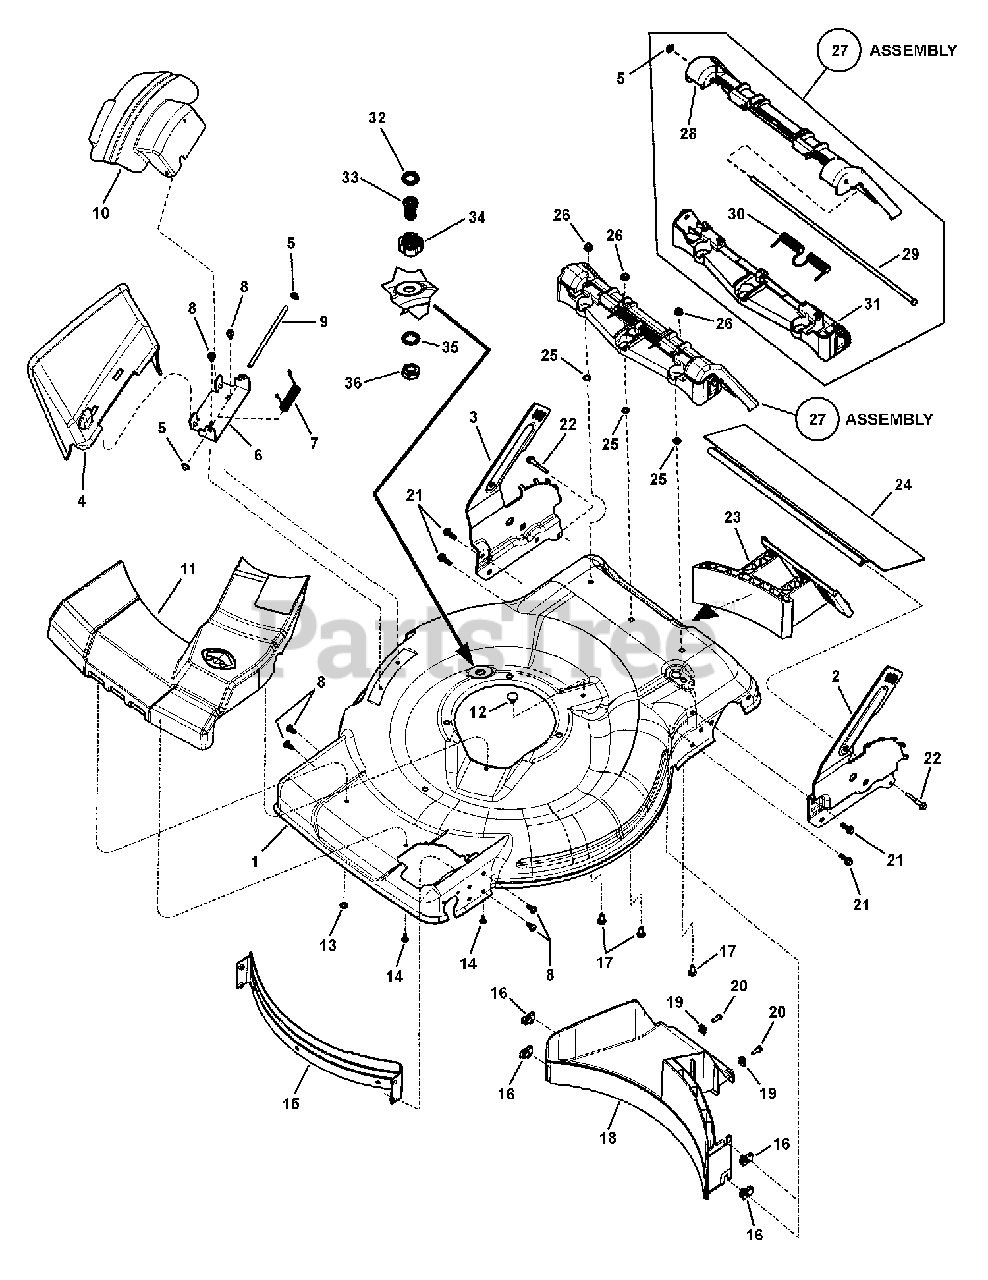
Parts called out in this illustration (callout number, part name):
1	DECK, 22" Front Wheel Drive, Washout
2	BRACKET, Lower Handle, LH, Hi-Wheel
3	BRACKET, Lower Handle, RH, Hi-Wheel
4	CHUTE, Side Discharge, 22" WBM
5	PUSHNUT, 1/4"
6	BRACKET, Chute
7	CHUTE SPRING, Torsion
8	SCREW, 1/4-20 x .550" Pan Head Torx (T-30)
9	ROD, Pivot
10	COVER, Mulching
11	COVER, SPX, Front Wheel Drive
12	PLUG, Panel, .25 x .61L, Black
13	NUT, 3/16" Push
14	SCREW, 4.8 x 1.59 x 13mm, Round Washer Head Hi-Lo (Torx)
15	BAFFLE, Front, Galv.
16	U-NUT, 1/4-20
17	BOLT, 1/4-20 x 5/8" Flat Head Square Neck, GR 5
18	REAR BAFFLE, Front Wheel Drive, WBM
19	SPEED NUT, #10-24 Retainer w/Extrusion
20	SCREW, #10-24 x 5/8" Hex Washer Face Self-Tap, GR 5
21	BOLT, 1/4-20 x 3/4" Hex Flange Lock, GR 5
22	BOLT, Drag Shield, 1/4-20 x 1-1/2"
23	PLUG, Mulching, 22" Deck
24	GUARD, Rear, 22"
25	RETAINER, 1/4" Bolt
26	NUT, 1/4-20 Hex Flange Lock
27	ASSEMBLY, Door, 22" WBM
28	DOOR, Rear Discharge
29	ROD, Pivot, Rear Door
30	SPRING, Torsion, Rear Door
31	DOOR HINGE, Rear Discharge
32	WASHER, Hose
33	ADAPTOR, Washout Port, WBM
34	COUPLING, Hose
35	WASHER, 5/8" Internal Tooth Lock YZ
36	NUT, 5/8-11, NC-2B Black Hex Jam
